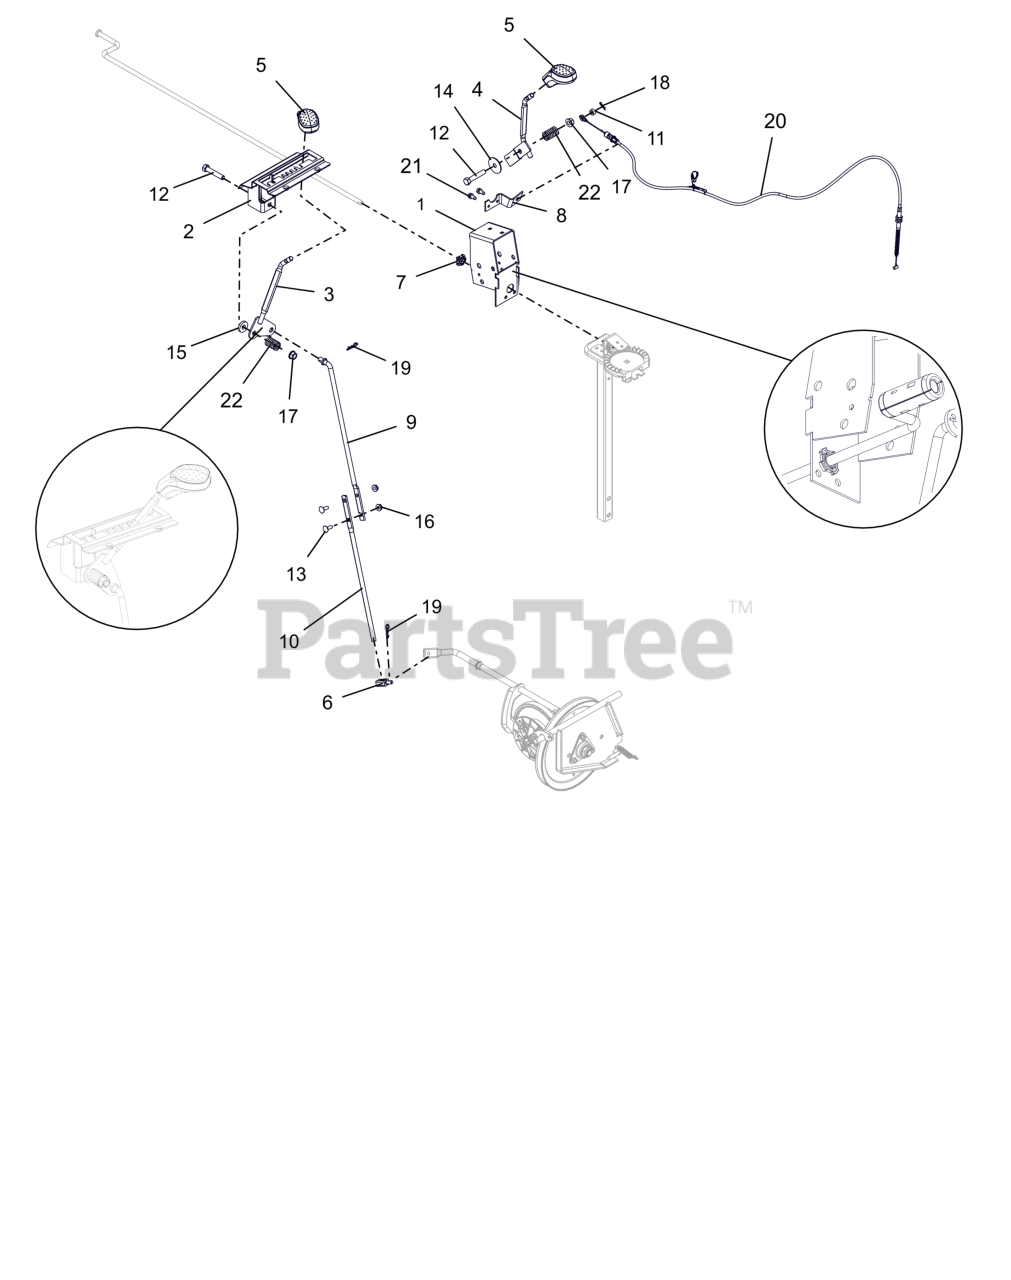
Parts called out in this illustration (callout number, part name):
1	WELDMENT, BRACKET INTERLOCK
2	WELDMENT, DETENT PLATE-COMPACT
3	LEVER, CONTROL-SHIFT(WELDMENT)
4	WELDMENT,SM DASH DEFL CONTROL
5	KNOB, CONTROL, DASH
6	PIVOT,SHIFT ROD .375-16(TRUNN)
7	CRANK BUSHING, NYLON CHUTE BK
8	ANCHOR, DEFLECTOR CABLE
9	ROD, SHIFT - UPPER
10	ROD, SHIFT - LOWER(SMALL DASH)
11	BSHG-SLV .265X.500X.219
12	BLT,HEX .38-16X2.00 G5 ZCC
13	BLT, RHSN .25-20X.750 G5 ZCC
14	WSHR,FLT .380X1.50X.062 ZCC
15	WSHR, FLT .406X1.00X.188 ZCC
16	NUT-LK-CTR-FLG .25-20 ZC120
17	NUT-LK-TOP-FLG .38-16 ZC120
18	PIN, HAIR #178 .06X.77 ZCC
19	PIN, HAIR #213 .08X1.19 ZCC
20	CABLE, DEFLECTOR - COMPACT
21	SCR-TAP .25-20X.50 HWH ZCC
22	SG-COMP .125X.781X1.250
